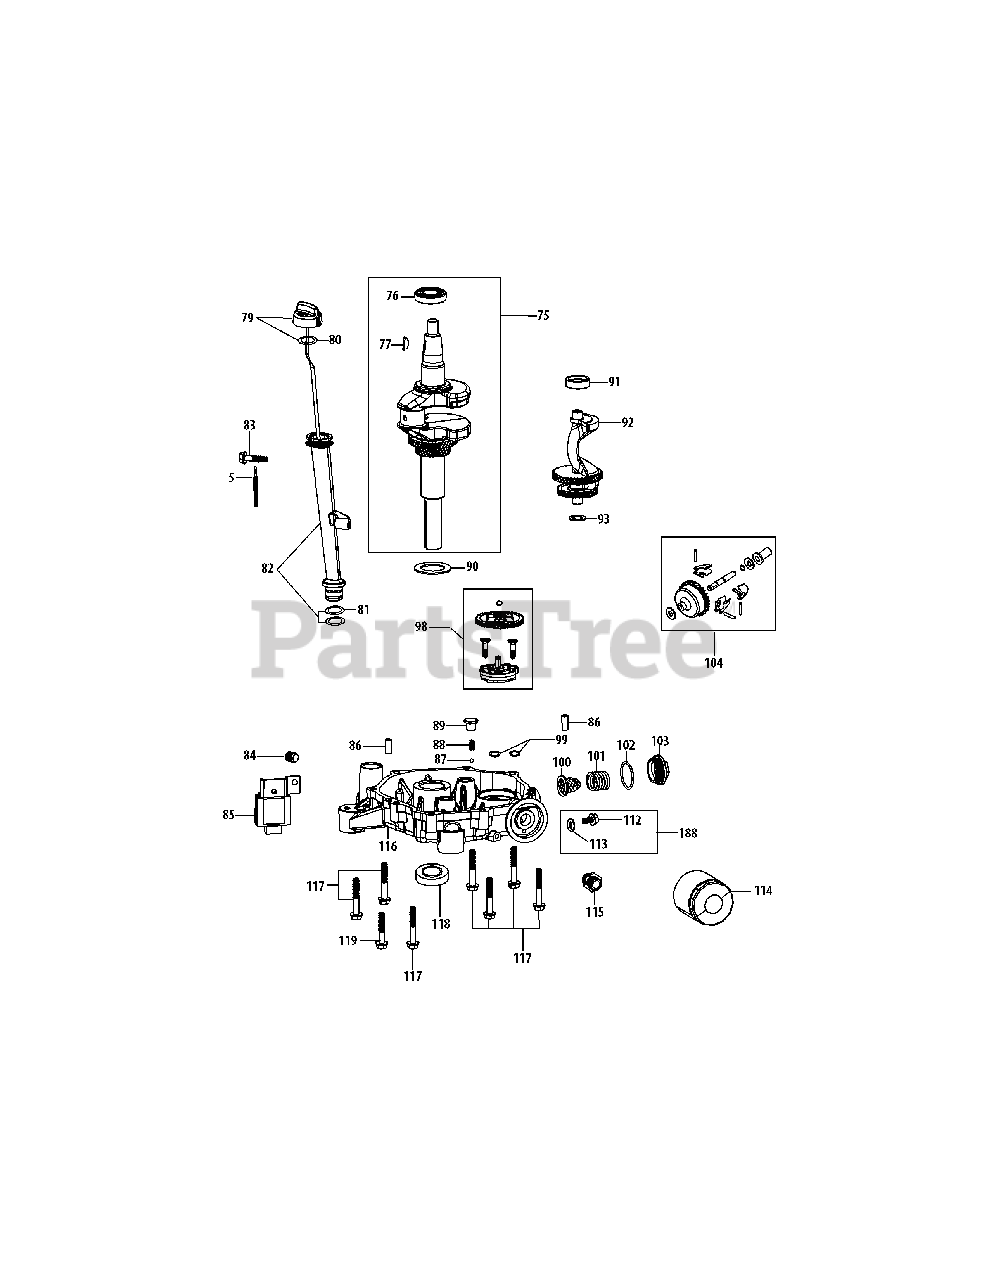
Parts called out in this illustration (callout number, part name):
5	Flexible Clamp
75	Crankshaft Assembly
76	Main Bearing
77	Woodruff Key
79	Dipstick Cover Assembly
80	Upper O-Ring
81	Lower O-Ring
82	Oil Fill Tube Asm
83	Bolt M6×35
84	Oil Drain Plug
85	Mounting Bracket
86	Dowel Pin 8×14
90	Crankshaft Thrust Washer
91	Balance Gear Shaft Bearing
92	Balance Gear Shaft Assembly
93	Balanceable Thrust Washer
98	Oil Pump Assembly
99	O-Ring 10×2.65
100	Sump Filter
101	Filter Spring
102	O-Ring 35.5×2.65
103	Filter Cover
104	Governor Gear/Shaft Assembly
112	Bolt M8×15
113	Oil Drain Plug Washer
114	Fine Oil Filter
115	Screw Joint Oil Filter Adapter
116	Crankcase Cover
117	Bolt M8×54
118	Upper Crankshaft Seal
119	Bolt M8×43
188	Oil Drain Plug Assembly
